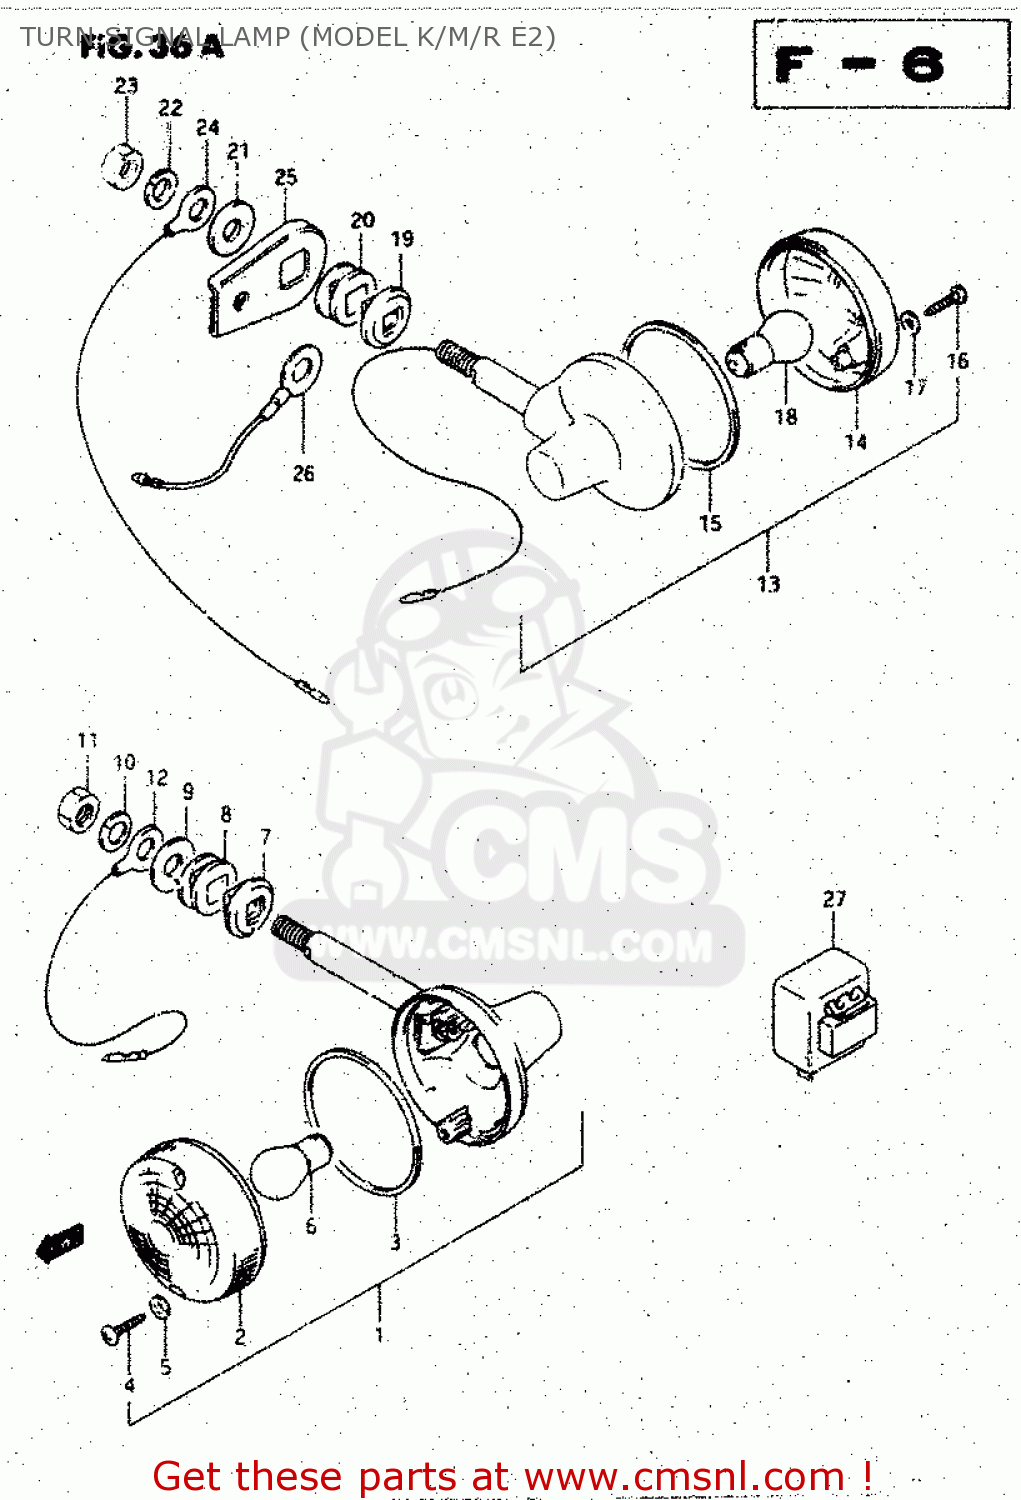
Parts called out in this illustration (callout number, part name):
1	LAMP ASSY, FRONT TURN SIGNAL
2	LENS
3	GASKET (NAS)
4	SCREW
5	GASKET (NAS)
6	BULB(12V21W)
7	SPACER
8	CUSHION
9	WASHER (10.5X30X2.3)
10	LOCK WASHER
11	NUT
12	LEAD WIRE,EARTH
13	LAMP ASSY,RR TURNSIGNAL
14	LENS
15	GASKET (NAS)
16	SCREW
17	GASKET (NAS)
18	BULB(12V21W)
19	SPACER
20	CUSHION
21	WASHER (10.5X30X2.3)
22	LOCK WASHER
23	NUT
24	LEAD WIRE,EARTH
25	BRACKET,RR TURNSIGNAL LAMP
26	LEAD WIRE,EARTH
27	RELAY ASSEMBLY,TURN SIGNAL
